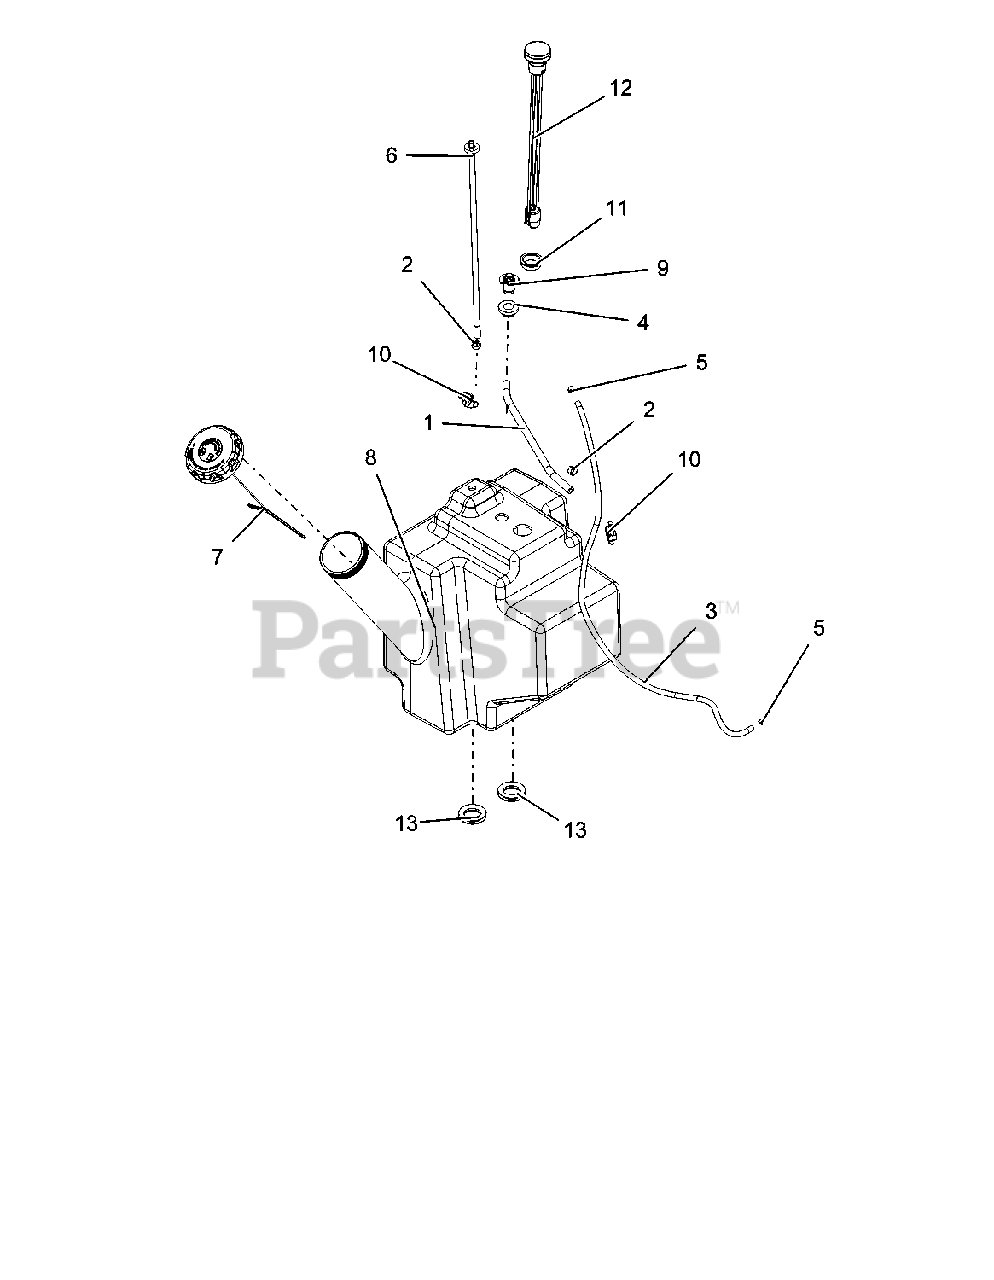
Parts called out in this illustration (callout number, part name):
1	HOSE, .25 LOW-PERM BULK GAS
2	CLAMP, FUEL LINE
3	HOSE, .188 LOW-PERM BULK GAS
4	GROMMET, REMOTE VENT NITRILE
5	CLAMP-HOSE, SPRING .188
6	ASS'Y, PROSTANCE FUEL PICK-UP
7	CAP, FUEL VENTIN AUTOLOCK
8	ASM, FUEL TANK
9	VALVE, 2-WAY
10	CLIP, T, .38-.50
11	GROMMET, FUEL GAUGE
12	GAUGE, REMOTE FUEL SEALED 15"
13	GROMMET 1.25ID X 1.5OD
